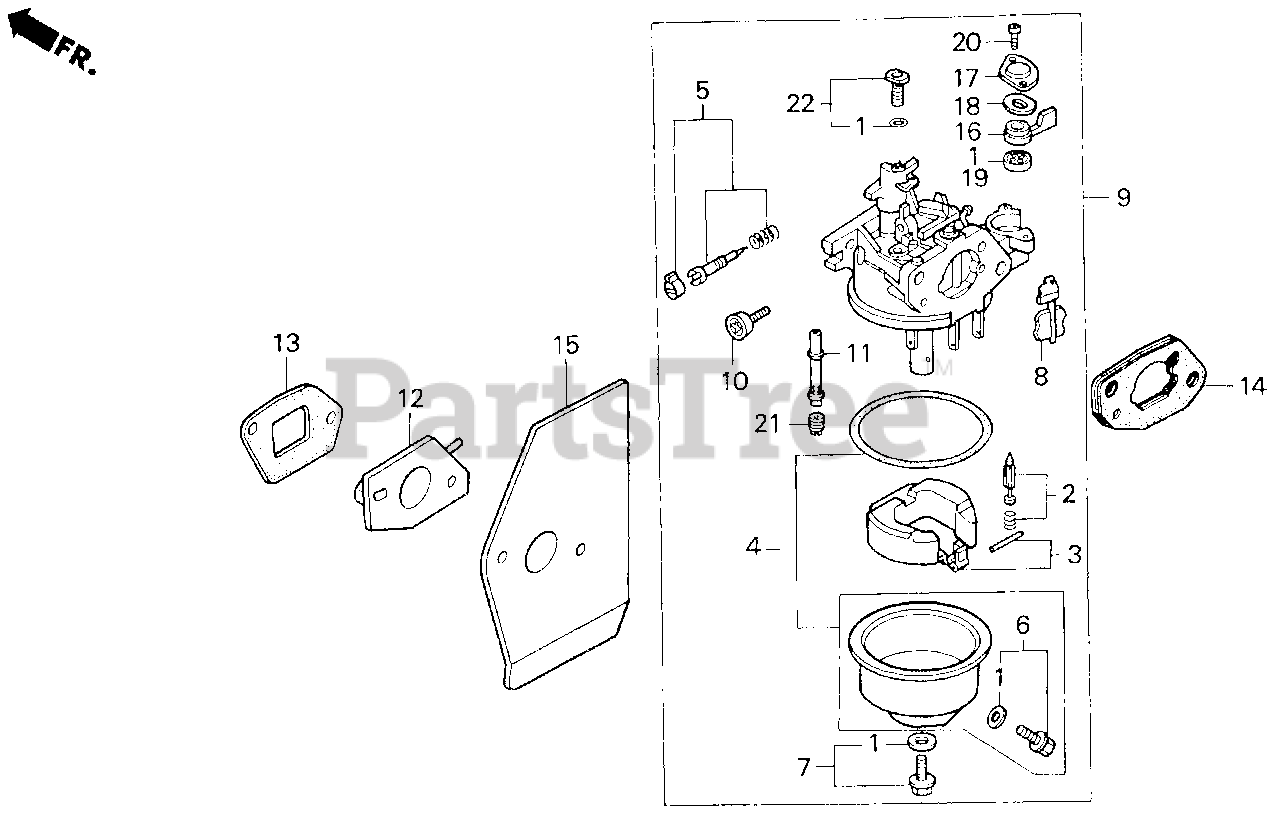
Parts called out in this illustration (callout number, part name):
1	GASKET SET
2	VALVE SET, FLOAT
3	FLOAT SET
4	CHAMBER SET, FLOAT
5	SCREW SET
6	SCREW SET, DRAIN
7	SCREW SET B
8	CHOKE SET
9	CARBURETOR ASSY. (BE66C A)
9	CARBURETOR ASSY. (BE66C B)
10	SCREW, THROTTLE STOP
11	NOZZLE, MAIN
12	INSULATOR, CARBURETOR
13	GASKET, INSULATOR
14	SPACER, CARBURETOR
15	GASKET, CARBURETOR
16	LEVER, VALVE
17	PLATE, LEVER SETTING
18	SPRING, VALVE LEVER
19	GASKET, VALVE
20	SCREW, PAN (3X6)
20	SCREW, PAN (3X8)
21	JET, MAIN (#62)
21	JET, MAIN (#60)
21	JET, MAIN (#65)
22	JET SET, PILOT (#35)
